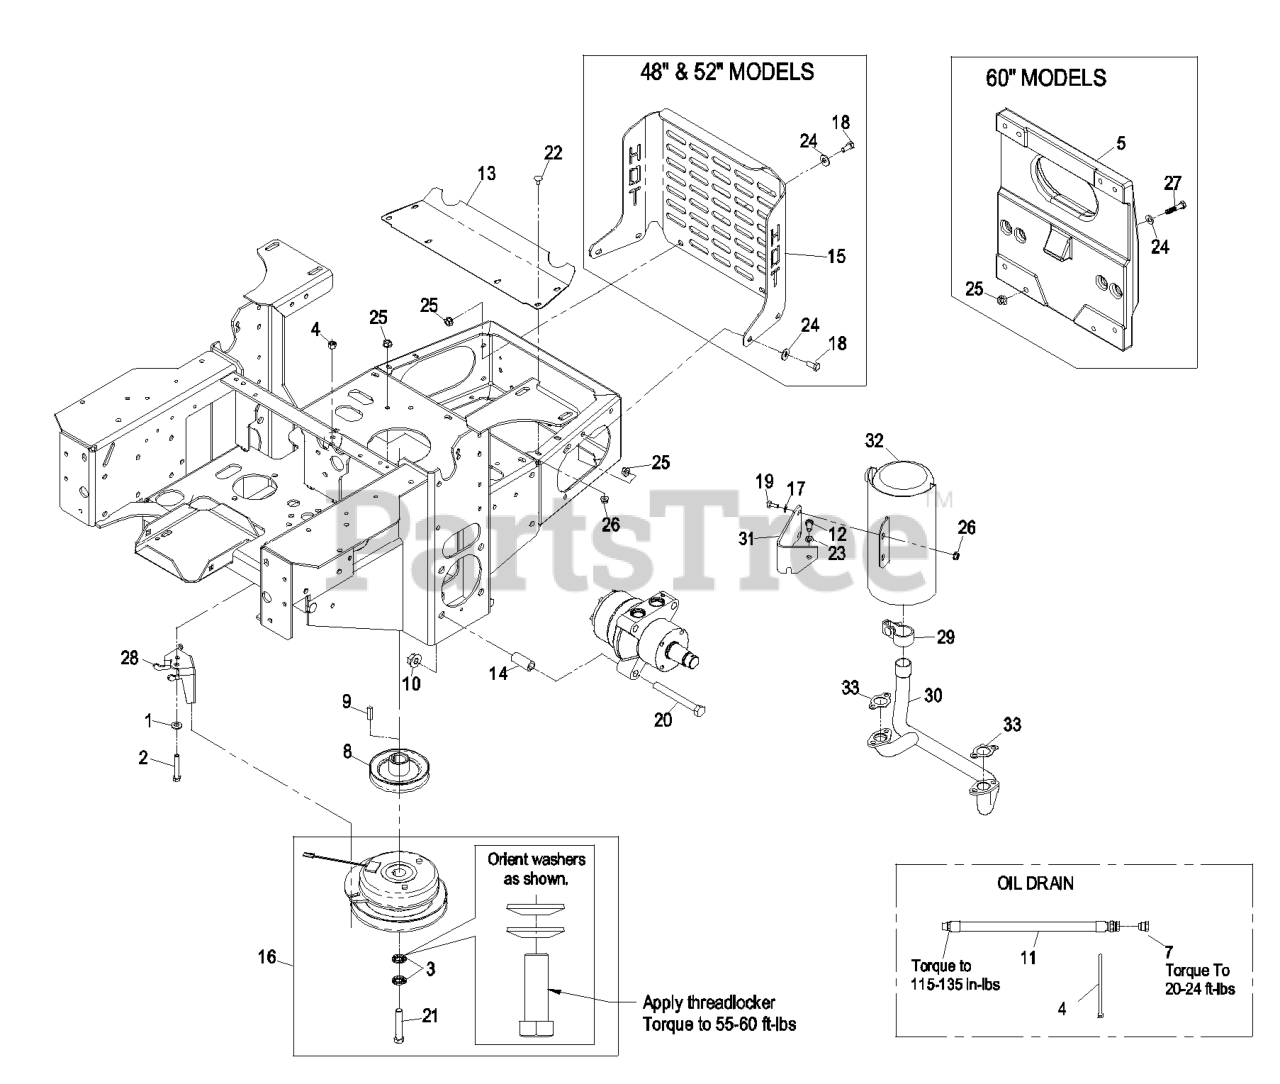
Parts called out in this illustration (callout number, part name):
1	WASHER-SPRING
2	SCREW-HH
3	WASHER-SPRING
4	CABLE TIE-PLASTIC
5	WEIGHT-NOTCHED, 60 LB
6	Bolt-Carriage 5/16-18 X 1 1/4
10	NUT-HHF
12	SCREW-HH
13	DEFLECTOR-SHORT
14	SPACER-MOTOR, WHEEL
15	BUMPER-REAR
16	KIT, CLUTCH LCT 48/52
17	WASHER-SPRING
18	SCREW-HH
19	SCREW-HH
20	SCREW-HH
21	SCREW-HH
22	SCREW-CARR
23	WASHER-LOCK
24	WASHER-PLAIN
25	NUT-HF
27	SCREW-HH
28	ANCHOR-CLUTCH
29	CLAMP-MUFFLER, 1.25 FLAT
31	BRACKET,EXHAUST 21BV
32	MUFFLER
